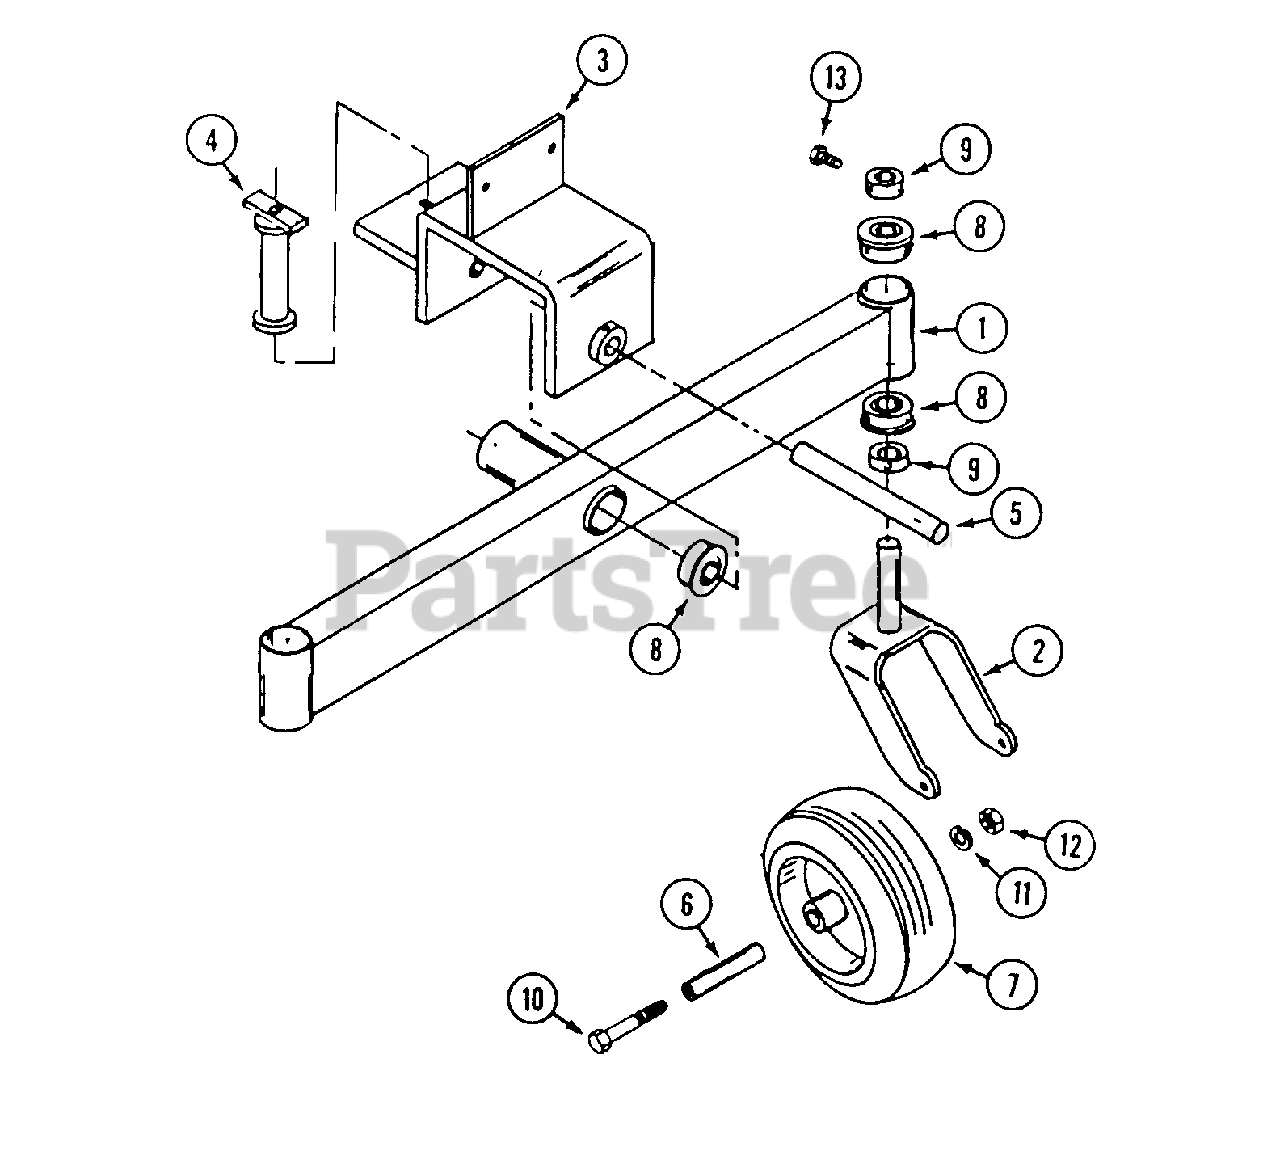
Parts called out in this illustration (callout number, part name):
1	AXLE - dual wheel
2	FORK - tail wheel
3	BRACKET - mounting
6	AXLE - wheel
7	WHEEL ASSEMBLY
9	COLLAR - set 1"
10	BOLT - 1/2" - 13 x 6-1/2"
11	LOCKWASHER - 1/2"
12	NUT - 1/2" - 13
13	SCREW - set 5/16" - 18 x 1/2" square head
